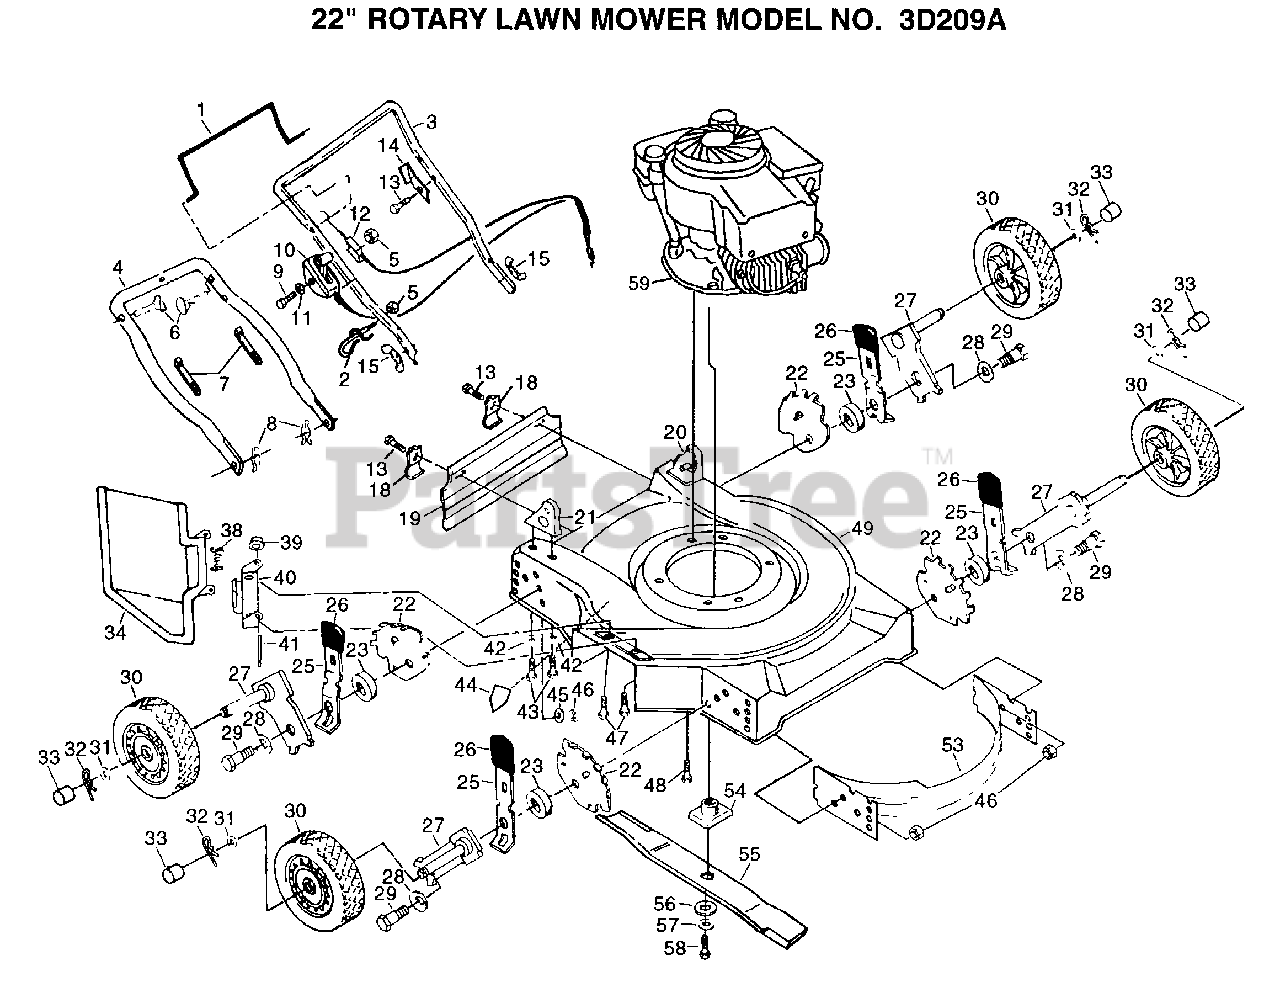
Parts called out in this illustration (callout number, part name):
1	CONTROL BAR PM
2	ROPE GUIDE
6	BOLT.HANDLE.LM
8	HAIRPIN COTTER
10	"CONTROL, THROTTLE"
11	WASHER PM
12	"CABLE,ENG ZONE CO"
13	TAPPING SCREW
14	"BRKT,UPSTOP"
15	"NUT,WING PM"
18	"BRKT,DEFL PM"
25	SPRING SELECTOR
26	KNOB PM
27	AXLE ARM
28	"WASHER, BELLEVIL."
30	WHEEL.ASM
31	WASHER
32	RETAINER CLIP PM
33	HUB CAP-PLASTIC
38	"SPRING,TORSION"
39	PUSH ON SPEED NUT
40	"BRKT,HSG"
41	"ROD,HINGE "
42	STEEL WASHER
43	SCREW
44	DECAL HYT
46	LOCKNUT PM
47	SCREW
48	SCREW
54	BLADE ADAPTOR
55	"BLADE.22"""
56	"WASHER,HARDEN"
57	LOCKWASHER
58	SCREW
